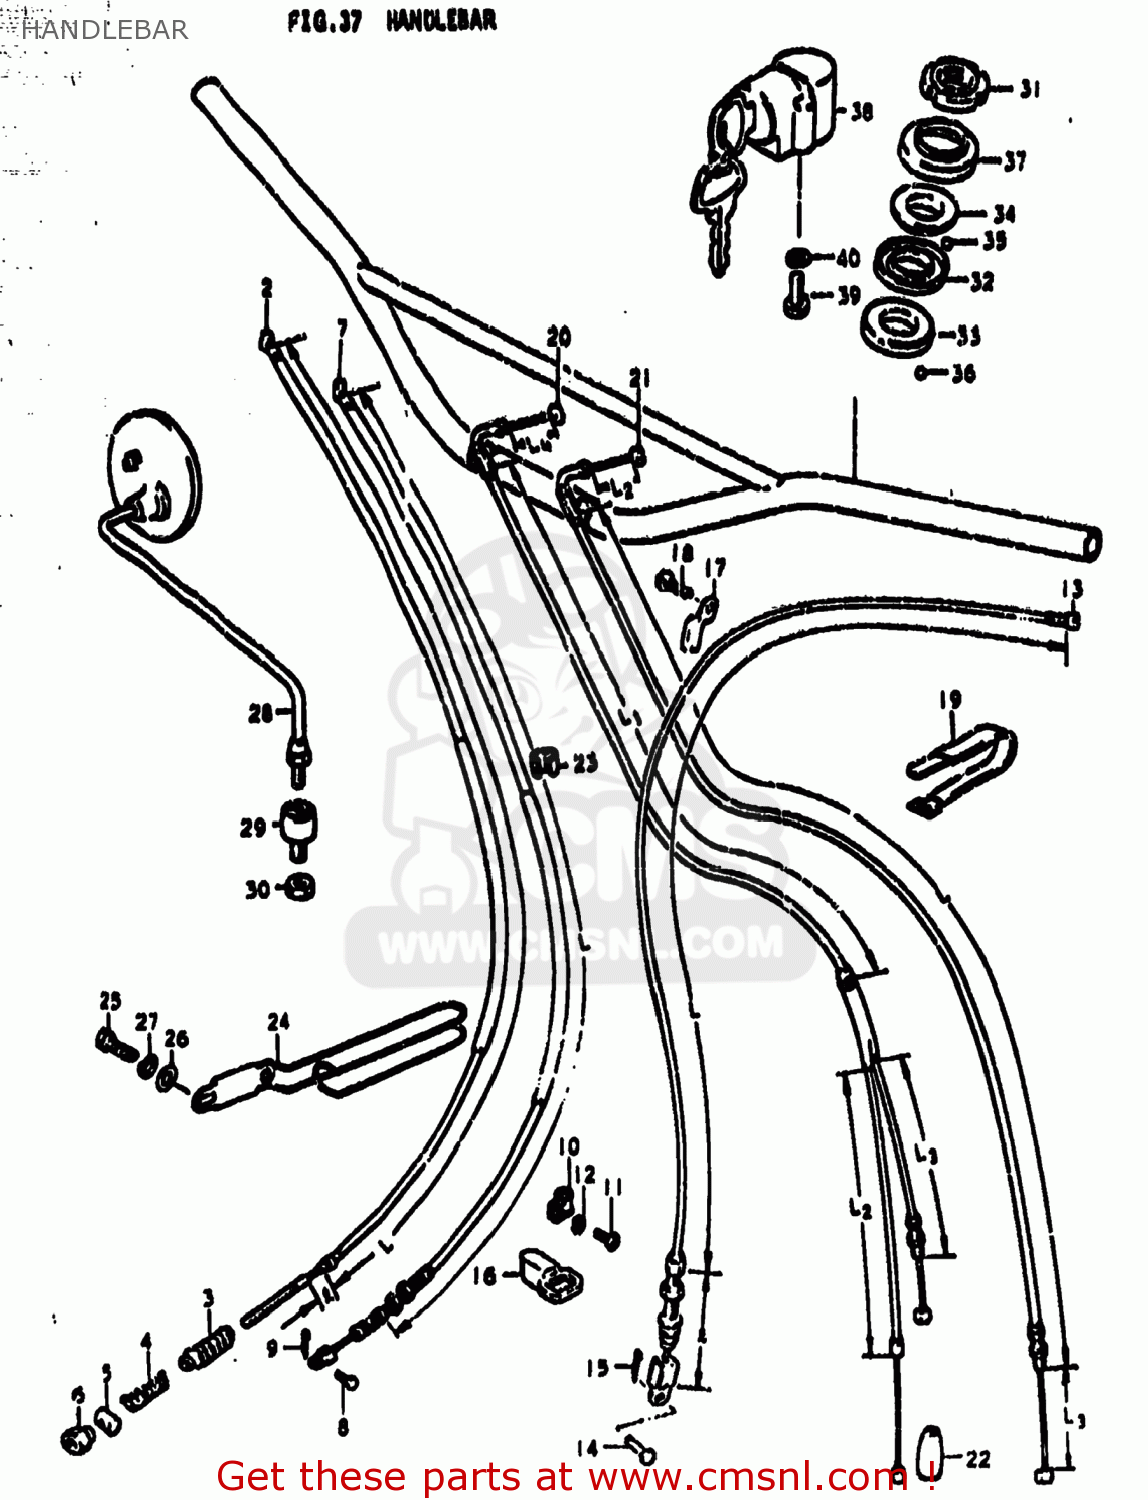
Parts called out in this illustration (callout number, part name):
1	HANDLEBAR
2	CABLE ASSEMBLY,FRONT BRAKE
3	SEAL,DUST(7X16X75)
4	SPRING
5	PIN,10X19
6	NUT
7	CABLE,FRONT BRAKE
8	PIN(L:13.5)
9	PIN
10	GUIDE,CABLE
11	SCREW
12	LOCK WASHER
13	CABLE ASSEMBLY,CLUTCH
14	PIN(L:15)
15	PIN
16	GUIDE,CABLE
17	CLAMP
18	SCREW
19	CLAMP
20	CABLE ASSEMBLY,THROTTLE
21	CABLE ASSEMBLY,THROTTLE
22	SEAL,DUST(7X18X30)
23	CLIP
24	GUIDE,CABLE
25	BOLT 8X12
26	WASHER
27	LOCK WASHER
28	MIRROR ASSEMBLY,LEFT
29	CUSHION,REAR VIEW MIRROR
30	NUT
31	NUT,STEERING STEM(25X44X10)
32	RACE,STEERING INNER UPR
33	LACE,STEERING INNER LWR
34	RACE,STEERING OUTER UPR
35	BALL
36	BALL
37	DUST SEAL,STEERING UPR
38	LOCK ASSEMBLY,STEERING
39	SCREW
40	LOCK WASHER
